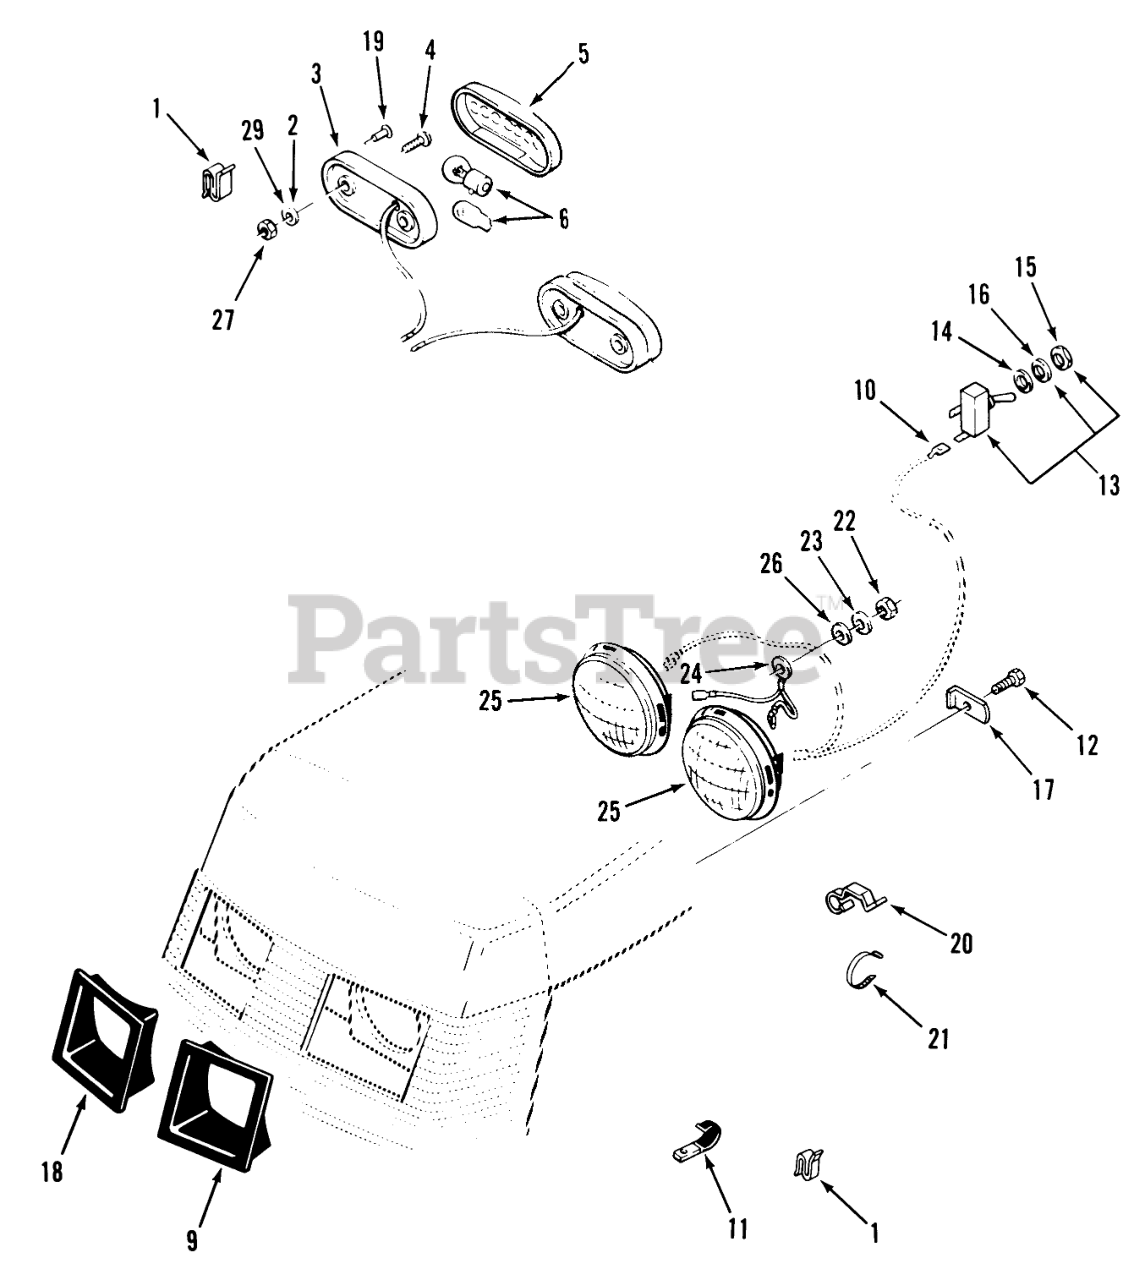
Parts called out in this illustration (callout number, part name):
1	SPEED CLIP
2	WASHER-LOCK
3	BASE-TAIL LIGHT
4	Screw
5	LENS-TAIL LIGHT
6	Bulb
9	BEZEL-HEADLIGHT, LH
10	Terminal
11	CLIP
12	Bolt
13	SWITCH-LIGHTS
14	Washer
16	TAB-WASHER
17	LOCK-HEADLIGHT
18	BEZEL-HEADLIGHT, RH
19	RIVET-POP
20	CLIP-WIRE
21	PLASTIC TIE
22	NUT-LOCK, NI
23	WASHER-LOCK, INTERNAL
24	LIGHT GROUND WIRE
25	HEADLAMP
26	WASHER-PLAIN
27	Nut
29	WASHER-FLAT
